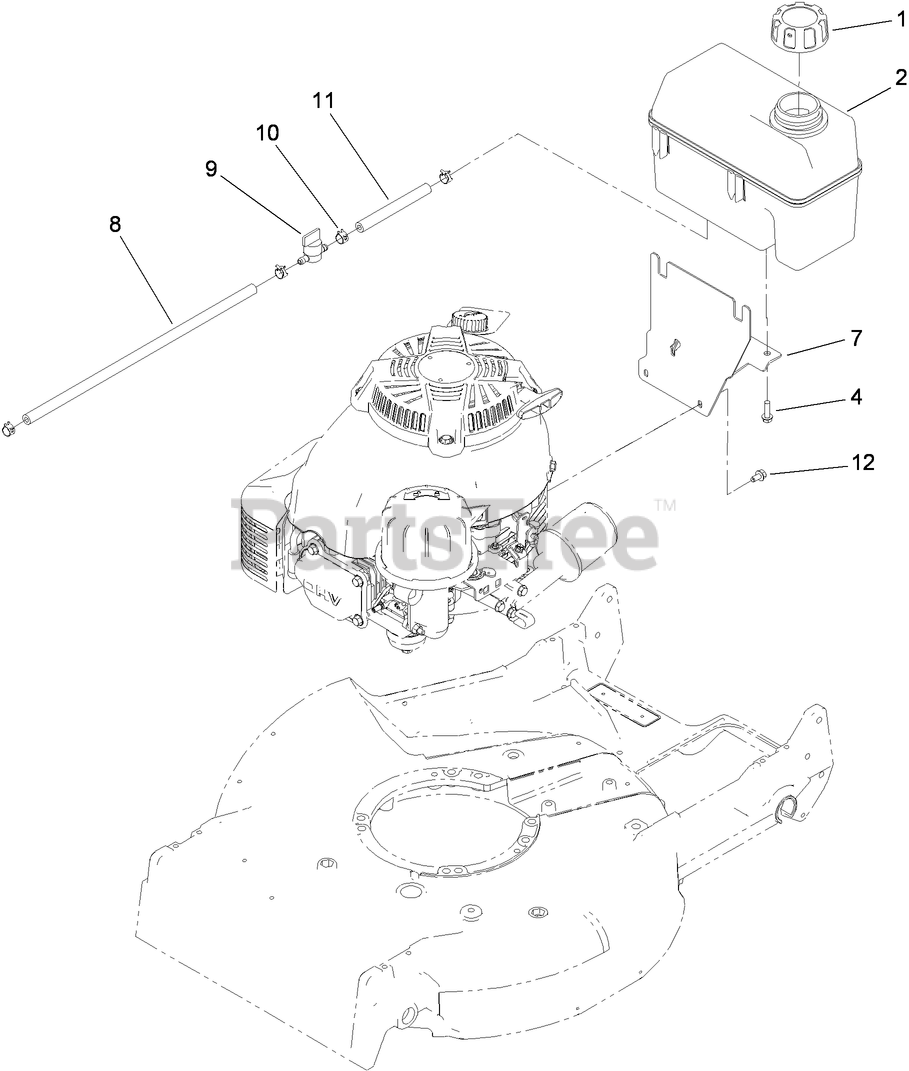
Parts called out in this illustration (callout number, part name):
1	CAP-GAS
2	TANK-FUEL
4	SCREW-HWH
7	MOUNT-TANK
8	HOSE-FUEL
9	VALVE-FUEL
10	CLAMP-HOSE
11	HOSE-FUEL
12	SCREW-HWH
